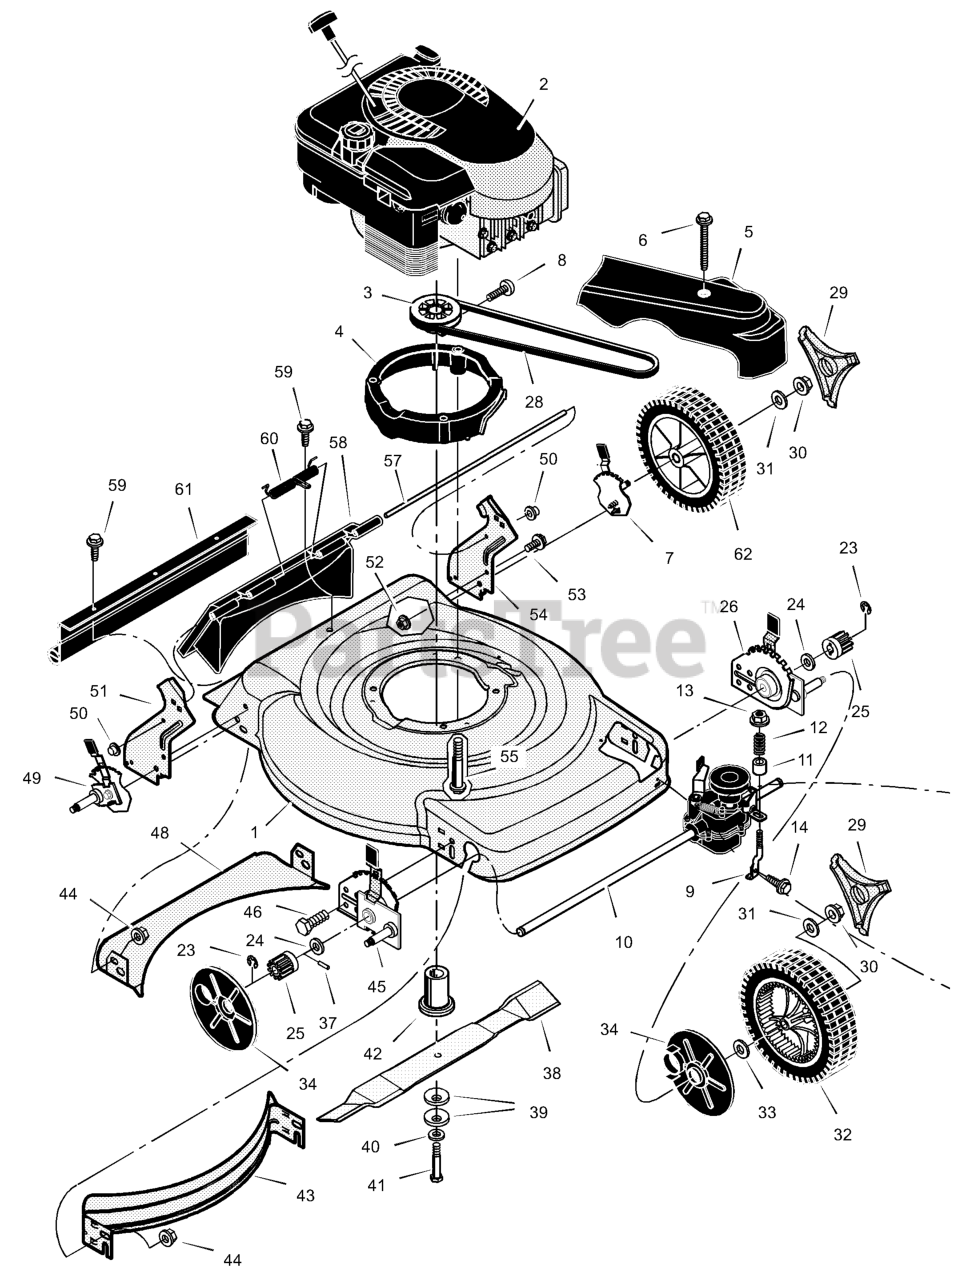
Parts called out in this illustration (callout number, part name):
1	Housing
2	Engine *
3	Pulley, Drive
4	Spacer, Engine
5	Cover, Belt (Black)
7	Adjuster, Left Rear Height
9	Support, Rod
10	Transmission *
12	Spring, Compression
13	Nut
25	Gear, Pinion
26	Adjuster, Left Front Height
29	Cap, Hub
30	Nut, Flange
31	Washer
32	Wheel & Tire, Front
34	Cover, Dust
37	Pin, Drive
39	Washer, Belleville
42	Adapter, Blade
43	Baffle, Front
44	Nut, Flange
45	Adjuster, Right Front Height
46	Bolt
48	Baffle, Rear
49	Adjuster, Right Rear Height
50	Push On Cap
51	Bracket, Right Handle
52	Nut, Flange
53	Bolt
54	Bracket, Left Handle
55	Bolt, Engine
57	Rod, Pivot
58	Door, Rear (Black)
61	Guard, Rear
62	Wheel & Tire, Rear
